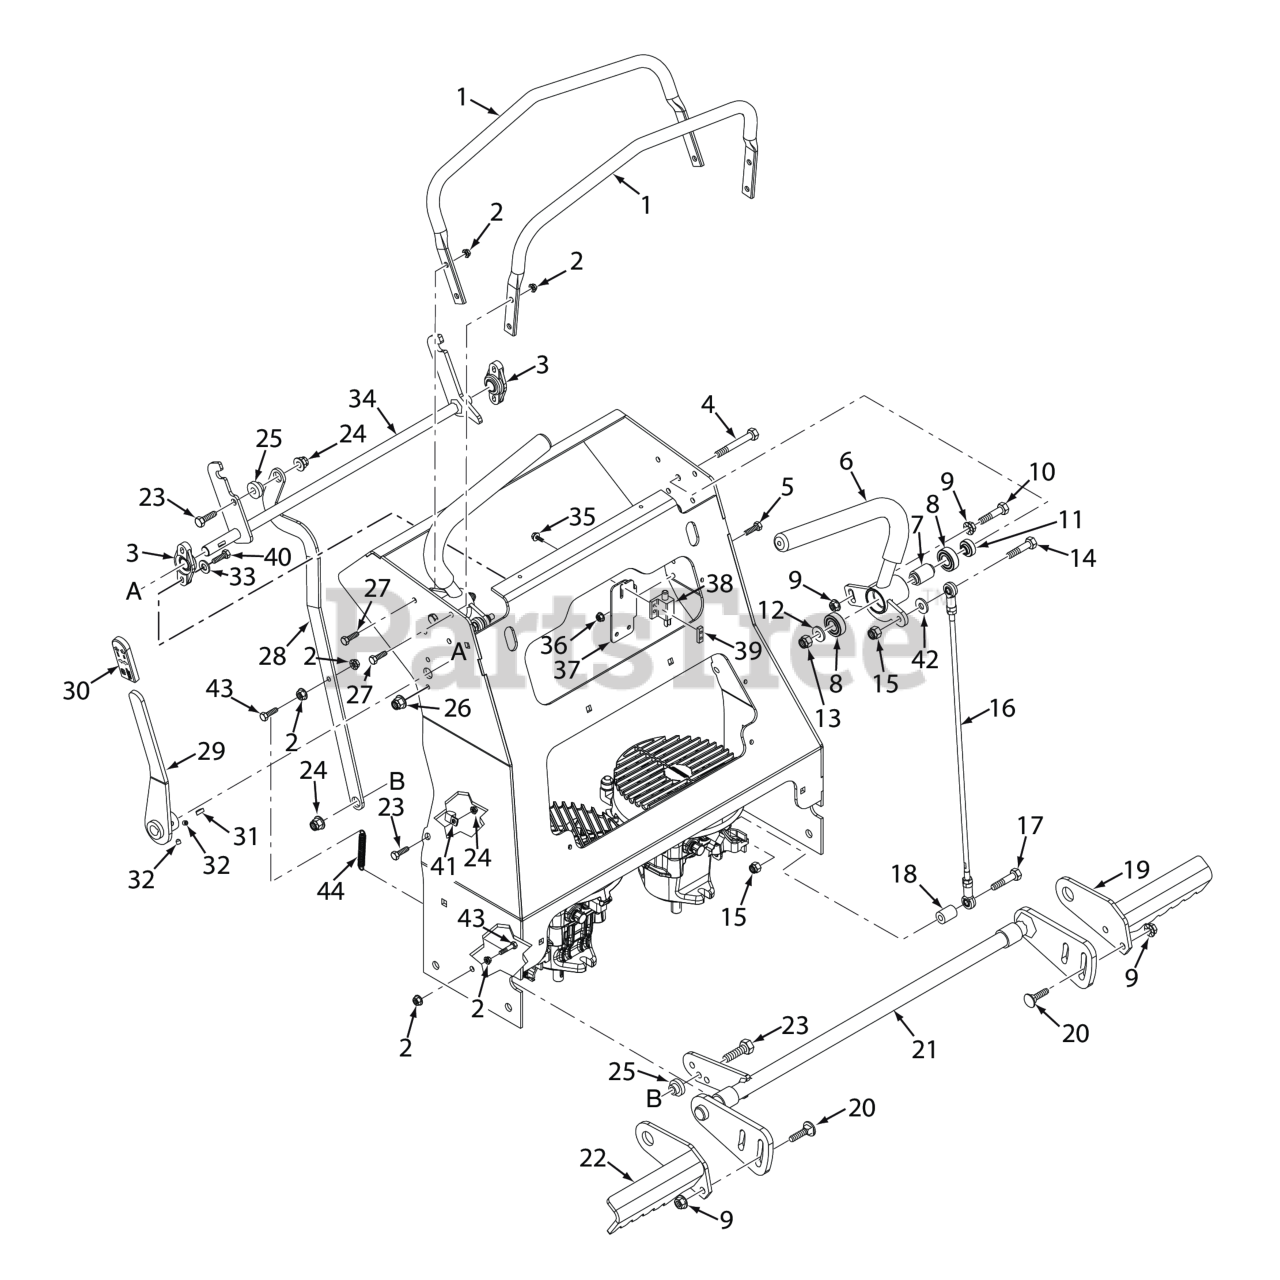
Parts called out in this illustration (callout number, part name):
1	Reference Bar
2	Nut, Serrated Flange 5/16-18 (Right Front Engine Mounting, Briggs and Kohler Only)
3	Bearing
4	Capscrew, Hex Head 3/8-16 x 3.25"
5	BOLT, HEX HEAD, 1/4-20 X 3/4 GR.5
6	Handlebar Assy., LH
6	Handllevar Assy., RH
7	Spacer, Bearing
8	BEARINGS, BALL, NEUTRAL RETURN
9	NUT, 3/8-16 SERRATED FLANGE HEX HEAD
10	Capscrew, Hex Head 3/8-16 x 2.0"
11	Spacer, Controls
12	Flatwasher, 3/8 (.391 x .938 x .105 HD) Grade 8
13	HEX NUT, ELASTIC STOP LOCK, 3/8-16
14	Bolt, 5/16 - 18 x 1 - 1/4" Hex Head
15	HEX NUT, ELASTIC STOP LOCK, 5/16-18
16	Linkage Assy., Steering
17	Bolt, Hex Head 5/16-18 x 2-1/2" (x3) (35BV & 37BV-EFI)
18	Spacer (excludes SVRII-36A)
19	Brake Paddle Weldment, RH
20	Carriage Bolt, 3/8-16 x 1.0"
21	Bellcrank Weldment, Brake
22	BRAKE PADDLE WLMT, LH
23	Bolt, Hex Head 3/8-16 x 1-1/4", Kawasaki FX / FS
24	Nut, Flange Elastic Stop Nut, 3/8-16
25	BUSHING, BRONZE - .376 ID X .627 OD
26	Nut, Flanged Elastic Stop 1/4-20
27	BOLT, SERRATED FLANGE HEX HEAD 5/16-18 X 3/4"
28	Link, Brake Engage
29	Brake Lever Assy. - SVRII (Incl. #30)
30	Grip, Parking Brake
31	KEY, WOODRUFF #61, 3/16 X 5/8
32	Set Screw 1/4-20 x 1/4"
33	Flatwasher, 1/4 (.281 x .625 x .065)
34	Lock Weldment, Neutral
35	Screw, Hex-Slotted Washer Head #10 32 x 3/4"
36	NUT, 1/4-20 SERRATED FLANGE HEX HEAD
37	Bracket, Neutral Switch
38	Switch, Interlock, Park Brake Normally Open
39	Plate, Threaded
40	Capscrew, Hex Head 1/4-20 x 1"
41	CLAMP, CABLE - 1.00
41	Cable Clamp, Double
42	Flatwasher, 5/16-.344 x .688 x .065 (48V / 52V)
43	Bolt, Hex Head 5/16-18 x 1-1/2" (Right Front Engine Mounting, Briggs and Kohler Only)
44	Spring, Deck Lift
